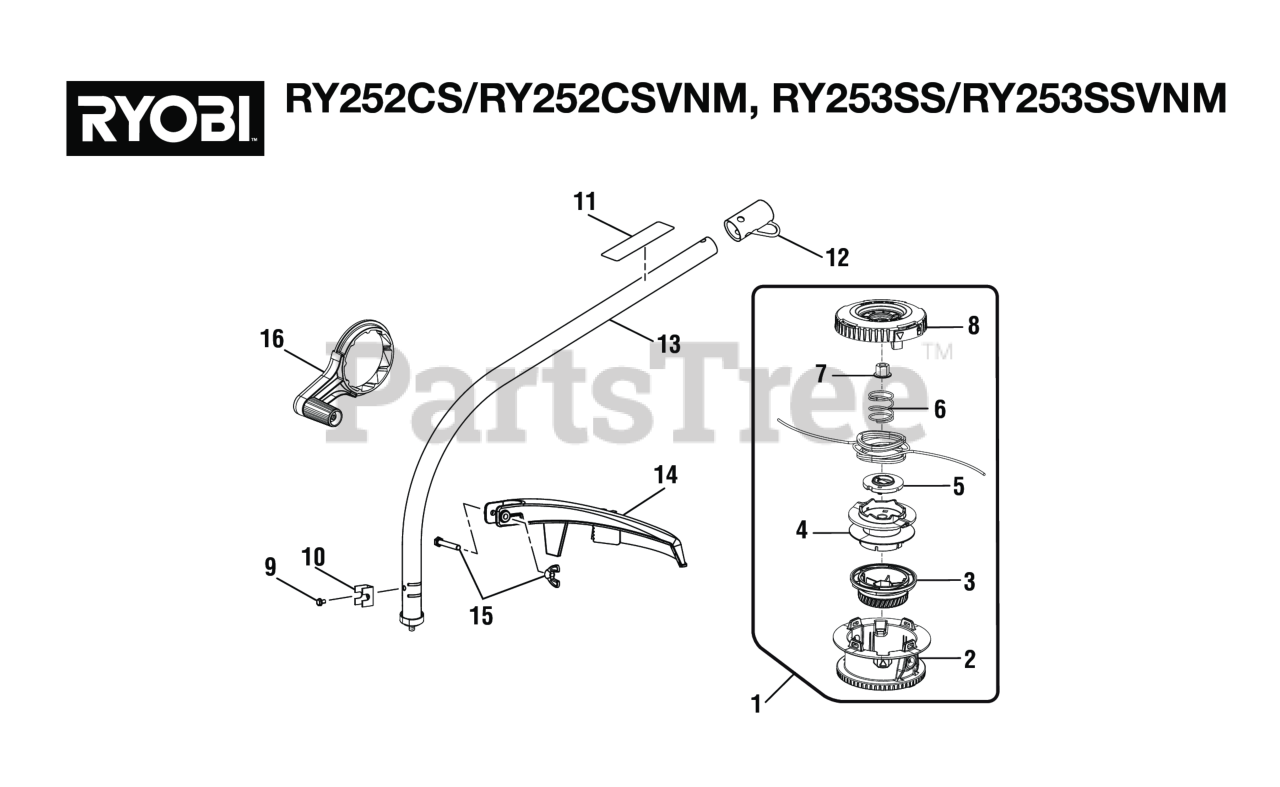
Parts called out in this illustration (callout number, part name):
1	Trimmer Head Assembly (.095) (Inc. Key Nos. 2-8)
2	Bump Head
3	Bump Knob (Green)
4	Spool Assembly
5	String Guide
6	Compression Spring
7	Flange Nut (M8)
8	Locking Assembly
9	Screw (#10-32 x 3/8 in., Hex Washer Hd. S.T.)
11	Warning Icon Label
12	Storage Hanger Cap
13	Curved Shaft Assembly (Inc. Key Nos. 9-12)
14	Grass Deflector Assembly
15	Fastener Parts Kit
16	Crank Handle
